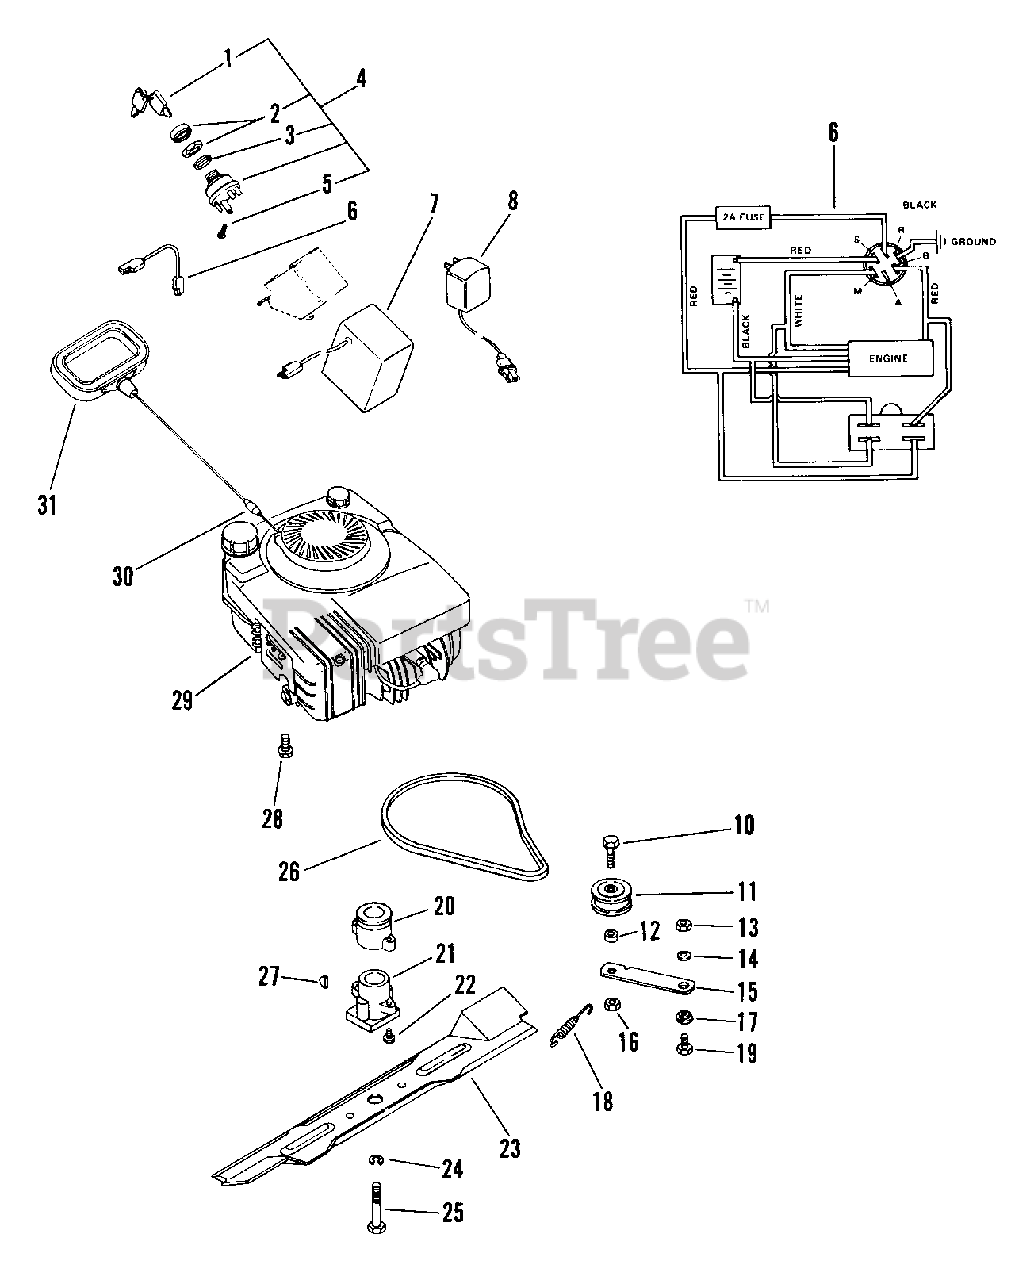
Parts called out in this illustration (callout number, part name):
1	KEY SET
2	NUT-PANEL .625-32 GRECO
2	CAP - IGNITION SWITCH
2	NUT .812-20 PL
3	WSHR-LK-INT .625X.045 PL
3	WSHR-LK-INT .813X.020 PL
4	KEY SWITCH
5	SCR-MCH 10-32X.32 SLRH PL
6	WIRE HARNESS
7	BATTERY
8	BATTERY CHARGER
8	BATTERY CHARGER UK FRIW0 56421
8	SEAT, ADJUSTER 07101
9	FUEL CAP
10	BLT-HEX .44-14X1.25 PL GR2
11	IDLER-FLAT 1.75 X .47
12	SPACER .52 X .45 X .34
13	NUT-LK .312-18 GR A PL
14	WSHR-FL-STL .323X.625X.062 PL
15	IDLER ARM
16	NUT-LK .437-14 GR A PL
17	BSHG-FLG .325X.501X.250X1.120
18	SG-TENS .043X.44X3.31 WLD 5.8
19	BLT-HEX .31-18X.75 PL GR2
20	TRACTION DRIVE SHEAVE
21	BLADE ADAPTER
22	SCR-TAP 10-24X1.0 HWH PL TR
23	21" MOWER BLADE
24	WSHR-LK .375X.094 MED PL
25	BLT-HEX .38-24X2.00 PL GR5
26	V-BELT, 3L-COGGED
27	KEY-WDRF .156X.625X.25 SAE 6
28	SCR-TAP .375-16X1.0 HWH PL TR
29	ENGINE TEC. 5HP BBC VECTOR
29	ENGINE TEC. 5 HP RECOIL VECTOR
29	ENGINE TEC. 5HP ELEC. VECTOR
29	ENGINE TEC. 5HP. RECOIL PLUS
29	ENGINE B/S 5HP RECOIL QUANTUM
30	ROPE BULLET
31	HANDLE, RECOIL START
